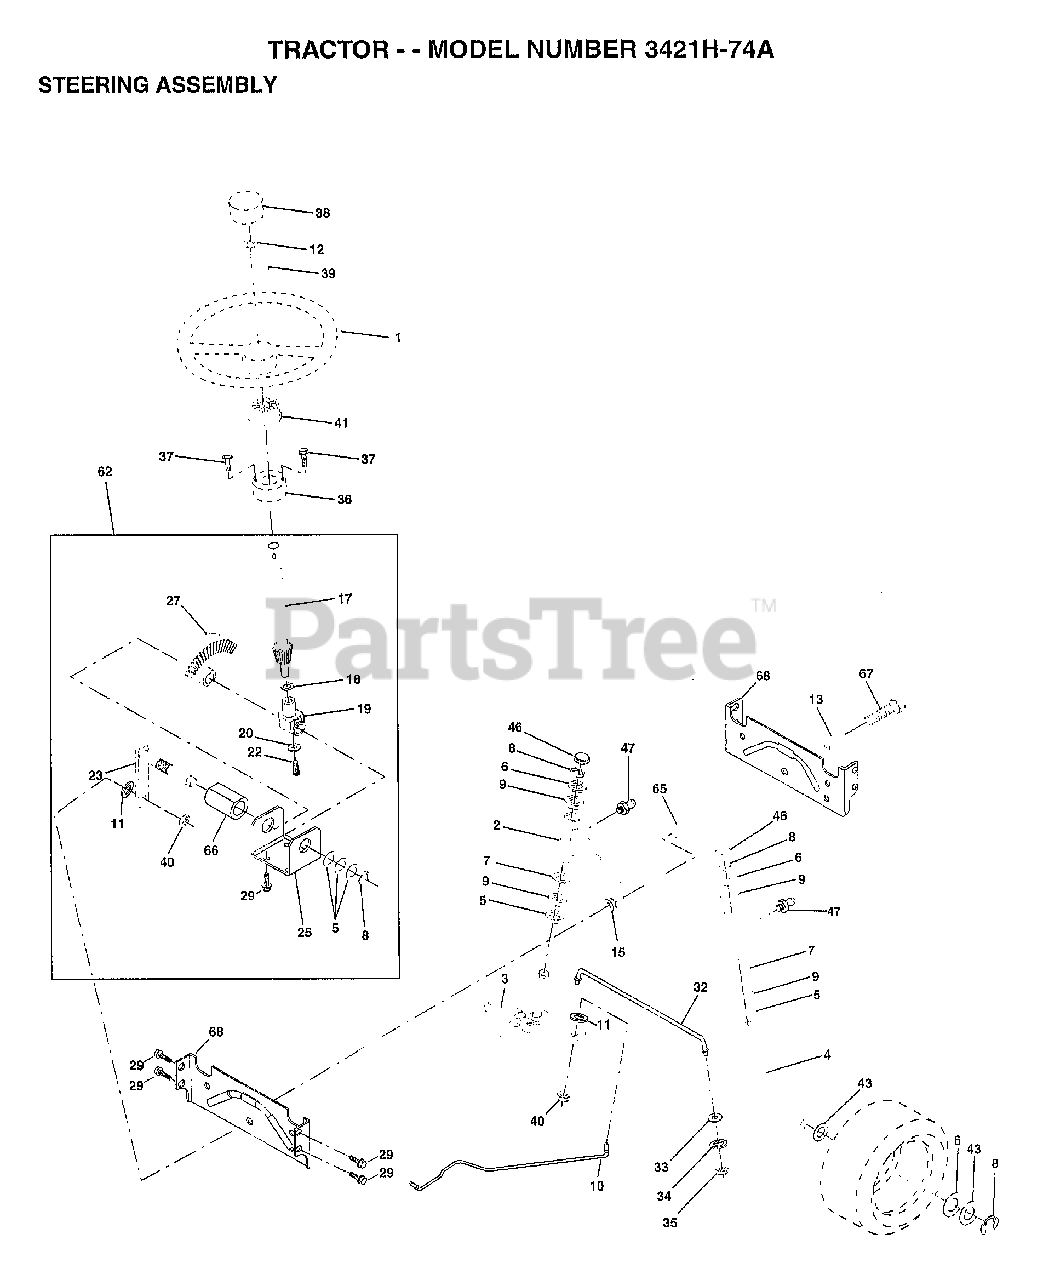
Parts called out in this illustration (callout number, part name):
2	AXLE ASM
3	SPINDLE.ASM.LH
5	WASHER .T
6	WASHER
7	WASHER
8	RING
9	COL. SRTG. BEAR.
10	DRAGLINK-STAMPED
11	LOCKWASHER
13	BEARING AXLE
15	"NUT-LOC,FLANGE LT"
17	SHAFT ASM STEERNG
18	THRUST WASHER
19	SUPPORT.SHAFT
22	SCREW HEX SOC1/4-
25	BRKT-STEERING
27	GEAR SECTOR
29	SCREW
32	ROD.TIE.19.75
33	WASHER M
34	LOCKWASHER
35	NUT.LOCK.5/16-24
36	BRKT-FOOTREST
37	"SCREW-TT,10-32 FL"
38	"INSERT,STR WHEEL"
39	WASHER
40	GRIPCO NUT
41	ADAPTER LT
43	WASHER
46	CAP
47	ZERK M
51	NUT
54	BOLT
62	KIT STEERING ASM
65	SPACER AXLE
66	"BEARING-ARM,PITMA"
67	BOLT
68	BRACE AXLE
